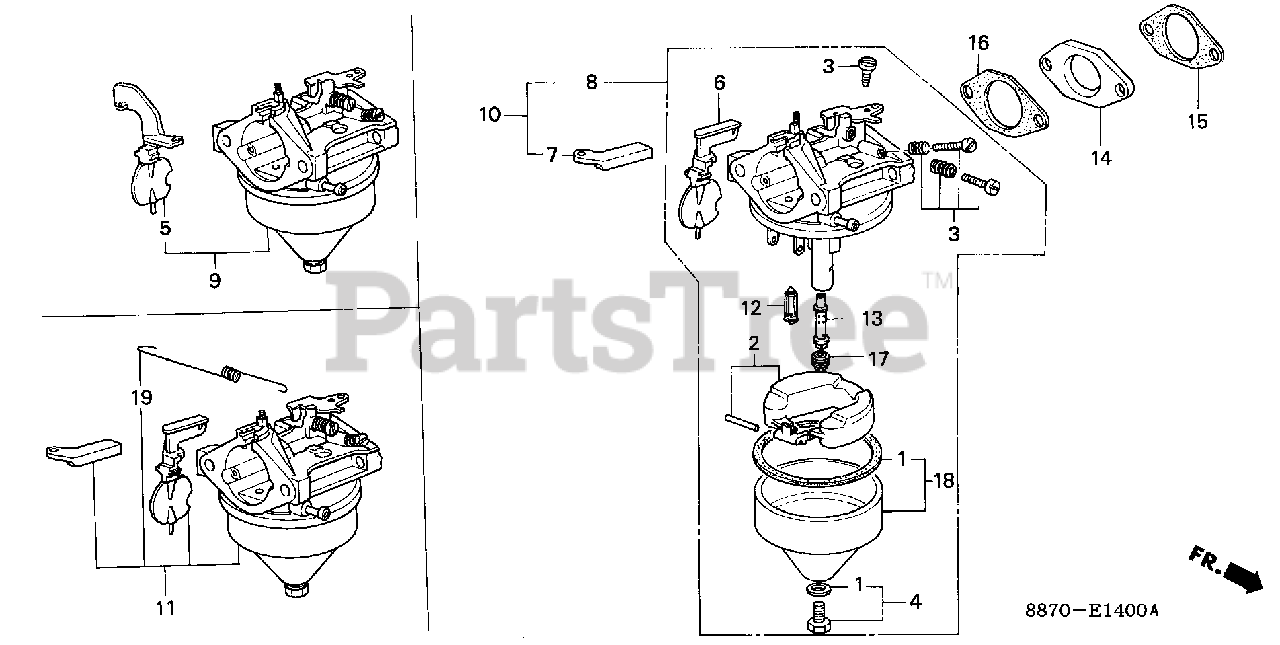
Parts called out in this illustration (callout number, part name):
1	GASKET SET
2	FLOAT SET (CARBURETOR NO.)
3	SCREW SET A (CARBURETOR NO.)
4	SCREW SET
5	CHOKE SET (CARBURETOR NO.)
6	CHOKE SET (CARBURETOR NO.)
7	ARM, CHOKE LEVER (CARBURETOR NO.)
8	CARBURETOR ASSY. (BB28A D)
9	CARBURETOR ASSY. (BB28A A)
10	CARBURETOR ASSY. (BB28A B)
11	CARBURETOR ASSY. (BB28A D)
12	VALVE, FLOAT (CARBURETOR NO.)
13	NOZZLE, MAIN (CARBURETOR NO.)
14	INSULATOR, CARBURETOR
15	GASKET, INSULATOR
16	GASKET, CARBURETOR
17	JET, MAIN (#55) Use up to Engine SN BB28A D.
17	JET, MAIN (#58) Use up to Engine SN BB28A D.
17	JET, MAIN (#60) Use up to Engine SN BB28A D.
17	JET, MAIN (#62) (CARBURETOR NO.)
18	CHAMBER SET, FLOAT
